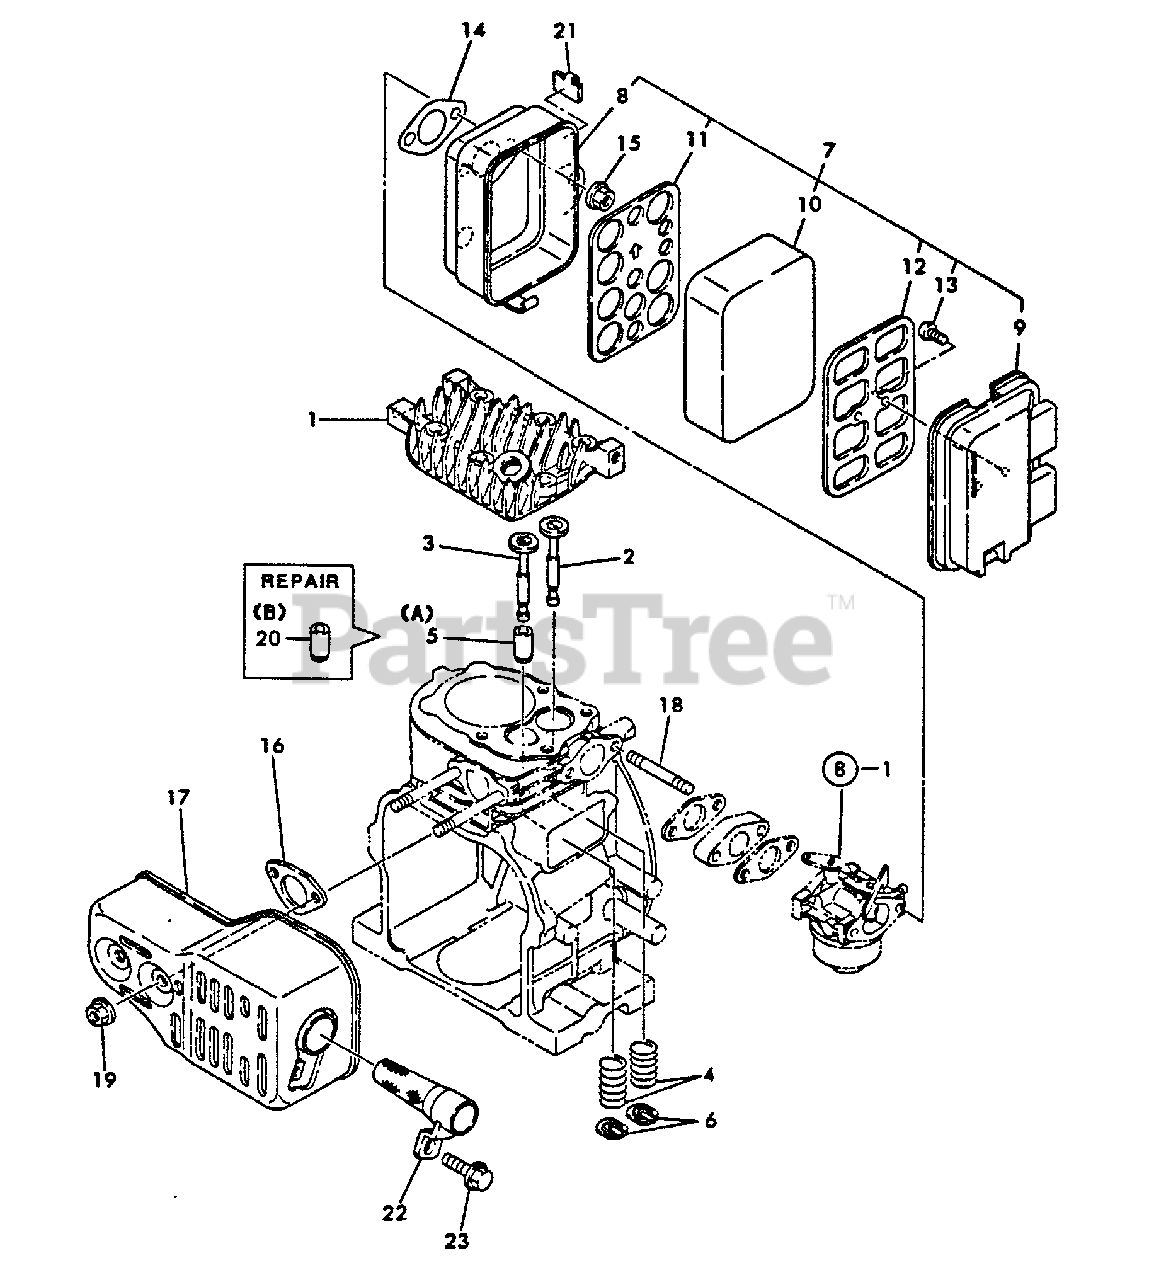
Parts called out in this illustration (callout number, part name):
1	HEAD, CYLINDER
2	VALVE, INTAKE
3	VALVE, EXHAUST
4	SPRING, VALVE
5	GUIDE, VALVE
6	RETAINER, VALVE
7	CLEANER ASSY, AIR
8	CASE, AIR FILTER
9	AIR FILTER COVER ASSY
10	FILTER, AIR
11	HOLDER (A), ELEMENT
12	HOLDER (B), ELEMENT
13	SCREW - 5×10
14	GASKET
15	U-NUT M6
16	GASKET, EXHAUST
17	MUFFLER
18	BOLT - 6×55
19	U-NUT M6
20	GUIDE, VALVE
21	CLAMP
22	SCREEN, SPARK ARRESTER
23	BOLT - 6×8 -- PLATED
